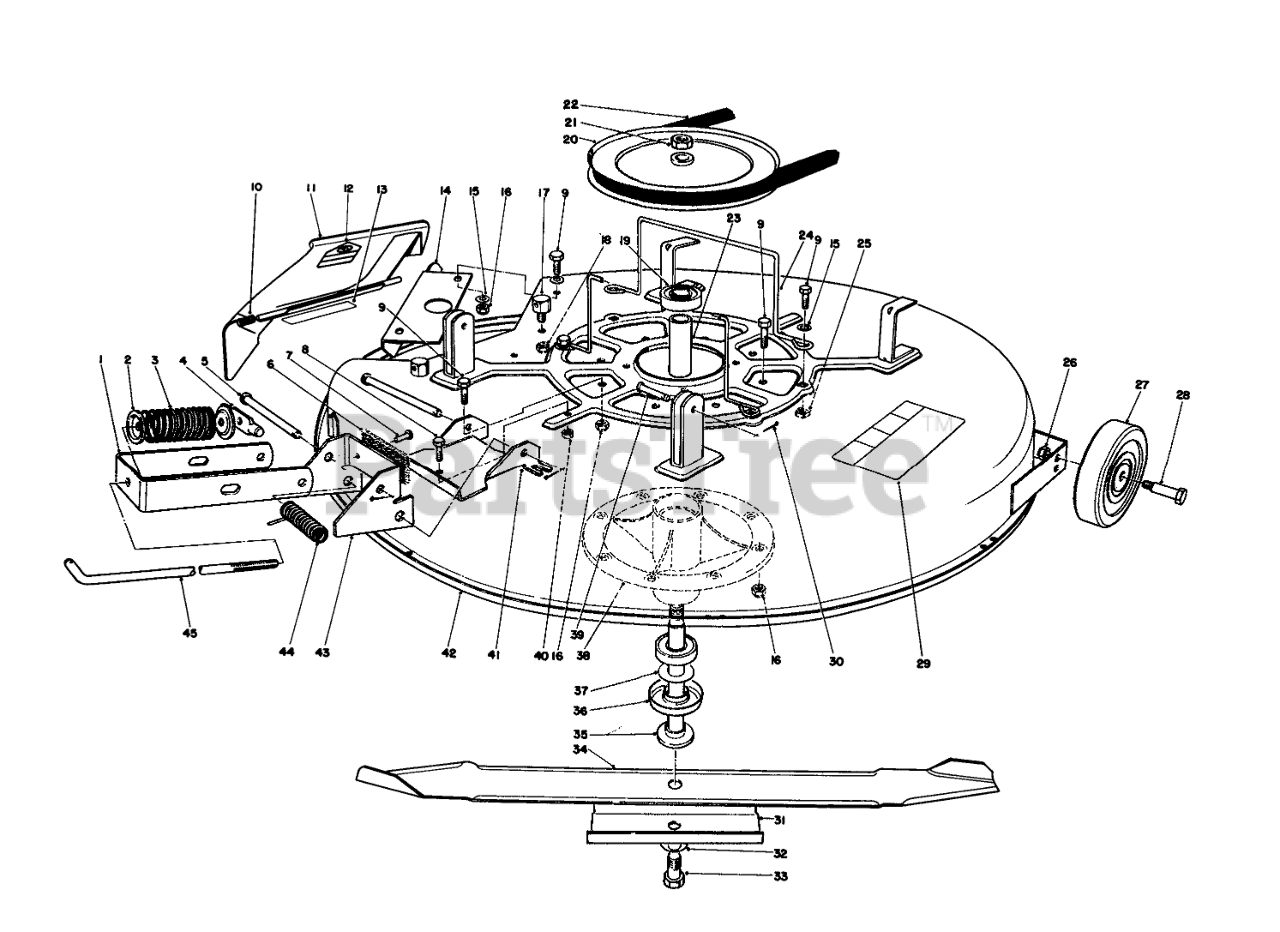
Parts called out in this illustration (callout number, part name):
1	Bracket-Engagement
2	RETAINER-SPR. TOP
3	SPRING-COMPRESSION
4	SHAFT-DECK ADJ.
5	PIN-CLEVIS
6	PAD-BRAKE
7	RIVET .187 X 7/16 BRASS
8	SCREW-HH
9	SCREW-HH
10	SPRING
11	Assembly-Deflector (Incl. Ref. #12)
12	DECAL-DANGER
13	DECAL-DANGER, DEFLECTOR
14	Baffle Deck
15	WASHER-PLAIN
16	NUT-LOCK, NI
17	POST-PIVOT
18	NUT-LOCK, SIDE
19	BEARING-BALL
20	PULLEY
21	NUT-HEX
22	V-BELT, DECK
23	SPACER-BEARING
24	GUIDE-BELT
25	NUT-RETAINER
26	NUT-LOCK, NI
27	WHEEL-DECK
28	BOLT-WHEEL
29	DECAL-DANGER, THROWN OBJECT
30	PIN-COTTER
31	STIFFENER
32	WASHER-BELLEVILLE
33	SCREW-HH
34	Blade
35	SHAFT-SPINDLE
36	SHIELD-BEARING
37	SPACER-HARDNED
38	SPINDLE
39	PIN-CLEVIS
40	NUT-HEX
41	Plate-Deck, Brake Mtg.
42	Deck-Cutting
43	Assembly-Brake (Incl. Ref. #6 & 73)
44	SPRING
45	ROD-ENGAGEMENT
